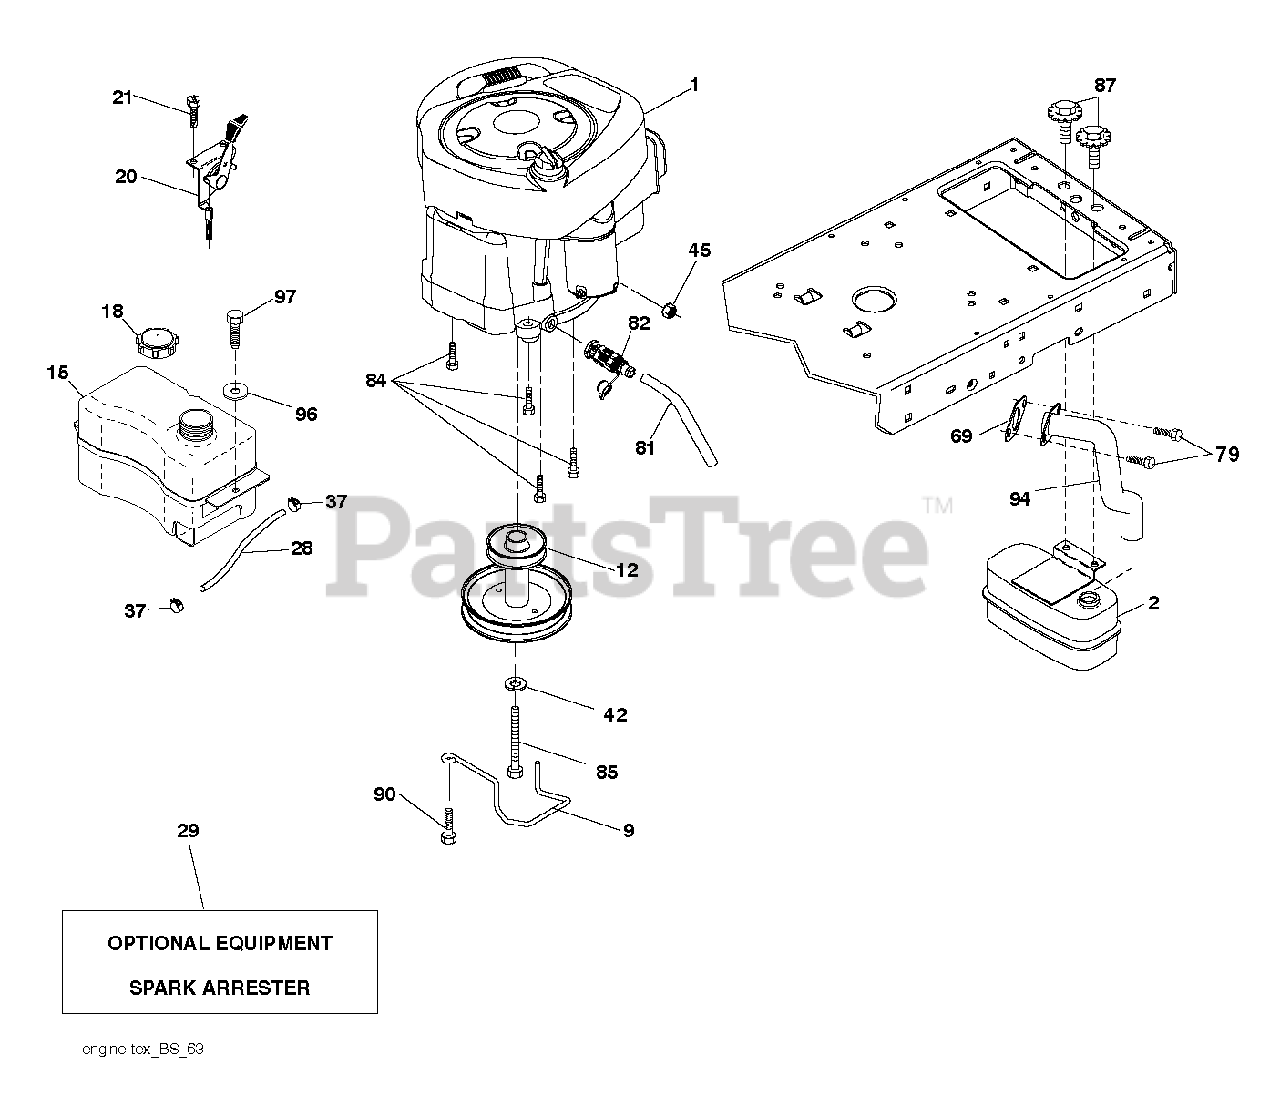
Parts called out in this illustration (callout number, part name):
2	MUFFLER.SINGLE.CYL.KOHL/B&S
9	KEEPER.BELT.ENGINE.4.2
12	PULLY ENGINE
15	TANK.ASM.FUEL.FR.2.5GA.
18	CAP ASM.FUEL.2.25"FR.
20	CONTROL.TH/CK.COBRA.KO
21	SCREW.#10 X 0.750.BOS
28	LINE.FUEL.20"FRONT.EMI
29	KIT.SPARK ARRESTOR 794945 B&S
37	HOSE CLAMP
42	LOCKWASHER
45	NUT
69	REPL BY 532 27 22-93
79	SCREW.SOCKET HD.5/16-1
81	TUBE, DRAIN OIL ASM.
82	VALUE.OIL.DRAIN
84	SCREW.3/8-16
85	BOLT HEX 7/16-20X4-1/4"
87	BOLT, 5/16-18 X 1 3/4
90	SCREW 3/8-16X1
94	EXHAUST.TUBE.B&S.
97	SCREW HEXWSHR 1/4-20X3/4
